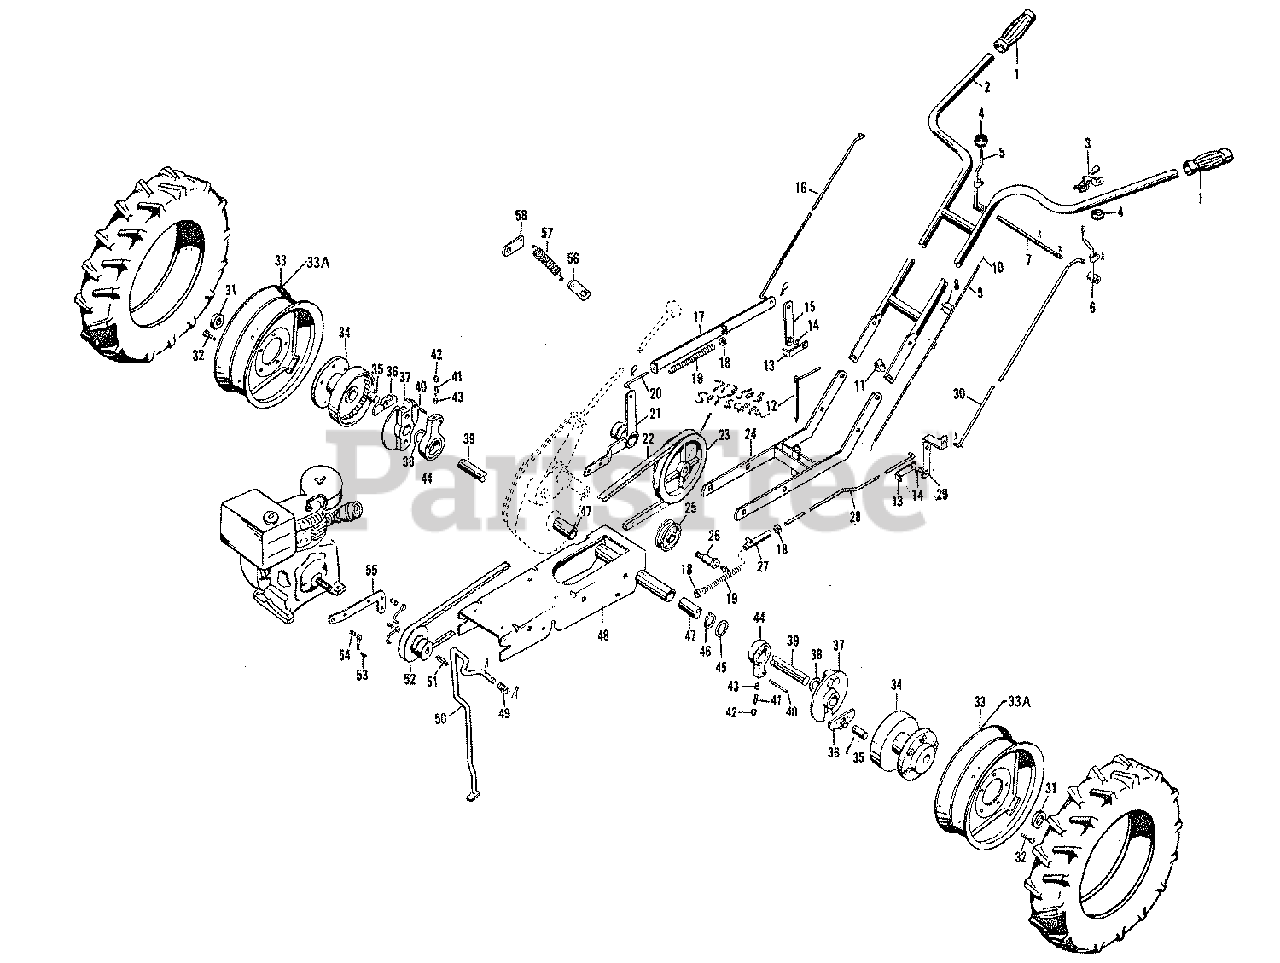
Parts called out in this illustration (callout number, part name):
1	HANDLE GRIP
2	HANDLE ASSEMBLY
3	THROTTLE CONTROL LEVER ASSEMBLY
4	CLUTCH LEVER BALL
5	R.H. CLUTCH LEVER ASSEMBLY
6	L.H. CLUTCH LEVER ASSEMBLY
7	LEVER SHAFT
8	CLIP, Cable
9	THROTTLE WIRE HOUSING
10	THROTTLE CONTROL WIRE
11	CLAMP, Throttle Wire Housing
12	HITCH PIN ASSEMBLY
13	STOP, Lever
15	LEVER, Lower Clutch Pivot
16	ROD, Upper Idler Clutch
17	IDLER CLUTCH ROD GUIDE ASSEMBLY
18	IDLER ROD SET COLLAR
19	ROD, Spring Idler
20	ROD, Lower Idler Clutch
21	IDLER LEVER ASSEMBLY
22	43" "V" BELT
23	TRANSMISSION PULLEY
24	FRAME ASSEMBLY
25	IDLER PULLEY ASSEMBLY
26	PIN, Idler Pulley
27	ROD SOCKET ASSEMBLY
28	ROD, Lower Idler
29	LEVER, Lower clutch
30	ROD, Upper Idler
31	COLLAR, Set
33	WHEELS, Drive (5-12 Tires)
33A	WHEELS, Drive (6-12 Tires)
34	HUB, Wheel
35	PIN, Ratchet Pawl
36	RATCHET PAWL ASSEMBLY
37	CAGE, Ratchet
40	RATCHET PAWL TRIP FINGER
41	TRIP FINGER HOLDER SPRING
42	SCREW, Headless, 7/16 -
43	TRIP FINGER HOLDER PLUG
44	HOLDER WITH BEARING ASSEMBLED
45	SPACER, Axle Housing
46	RING, Retaining
47	BEARING, Axle
48	BASE ASSEMBLY
49	SPRING, Stand
50	STAND ASSEMBLY
51	KEY FOR ENGINE PULLEY
52	ENGINE PULLEY
53	STOP, Belt
55	BELT STOP HOLDER
56	SPRING HOLDER, Lower
58	SPRING HOLDER, Upper
